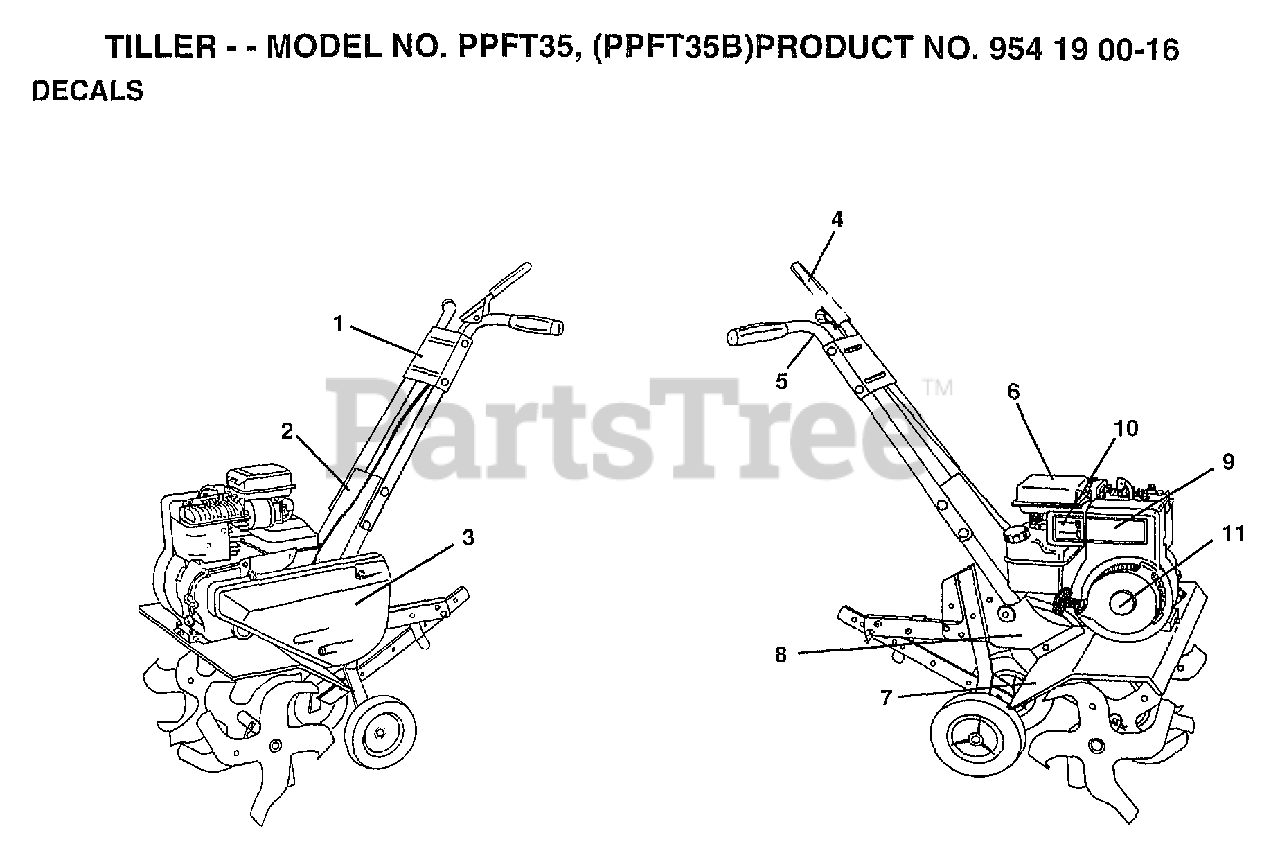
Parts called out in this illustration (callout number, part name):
1	DECAL.LOGO.CONTROL
2	DECAL.HP.CONTROL
4	DECAL, TINE CONTROL
5	DECAL HAND PLACEMENT
6	DECAL.CAUTION
7	DECAL WARNING ROTATING TINES
8	RETAINER-SPRING
9	DECAL-BRIGGS AND STRATTON
10	DECAL-SPEED CONTROL
11	DECAL-3.5 HP
